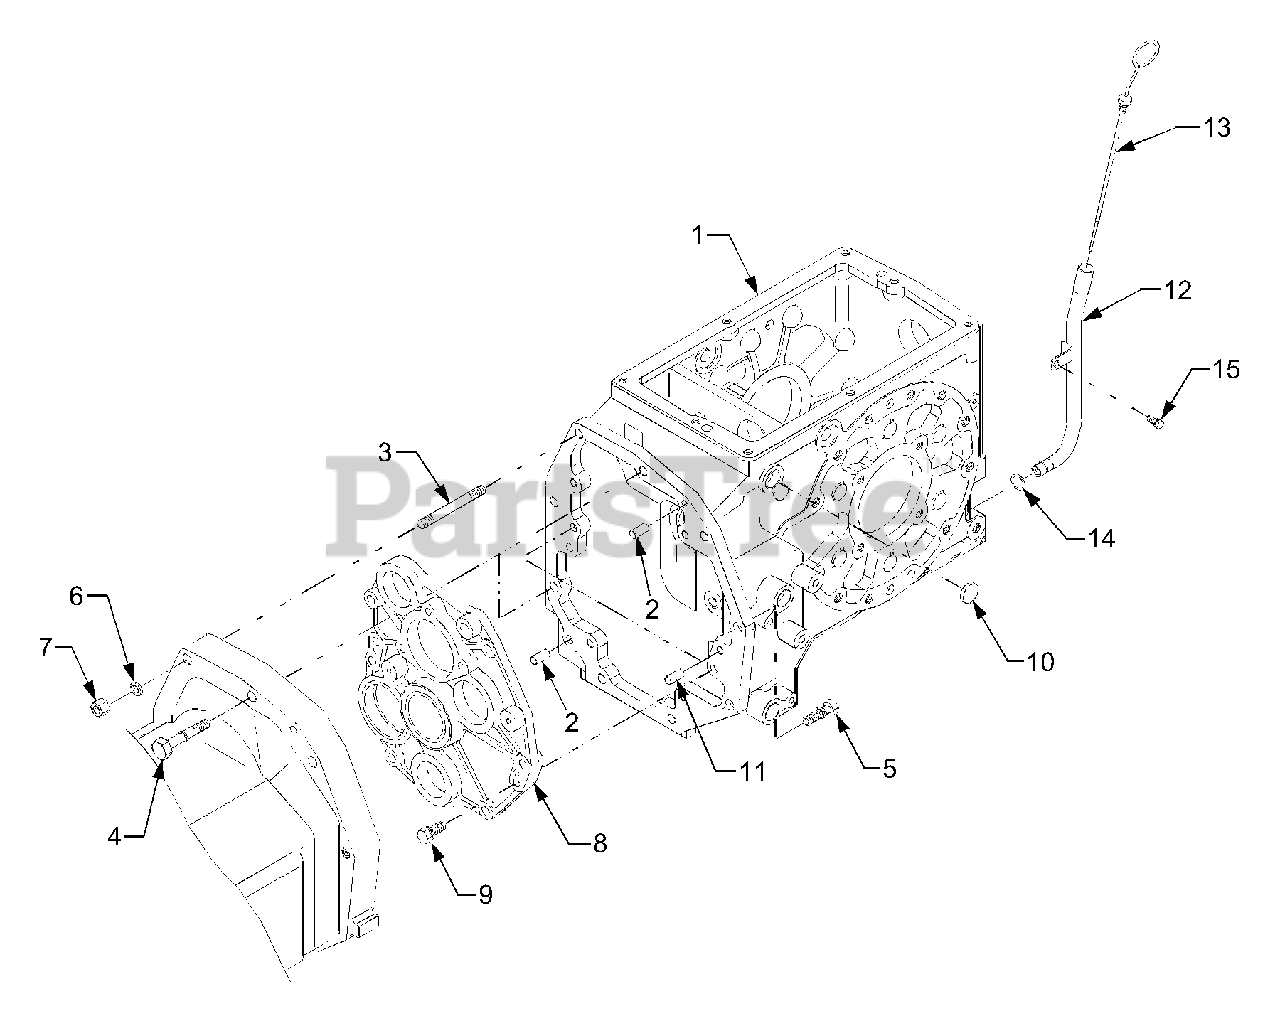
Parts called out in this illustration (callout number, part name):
1	Case, Transmission
2	Pin, Straight
6	Washer, Spring
8	Cover, Bearing
10	Plug, Expantion
11	Pin, Straight
12	Guide, Oil Gage
13	Gauge, Oil
